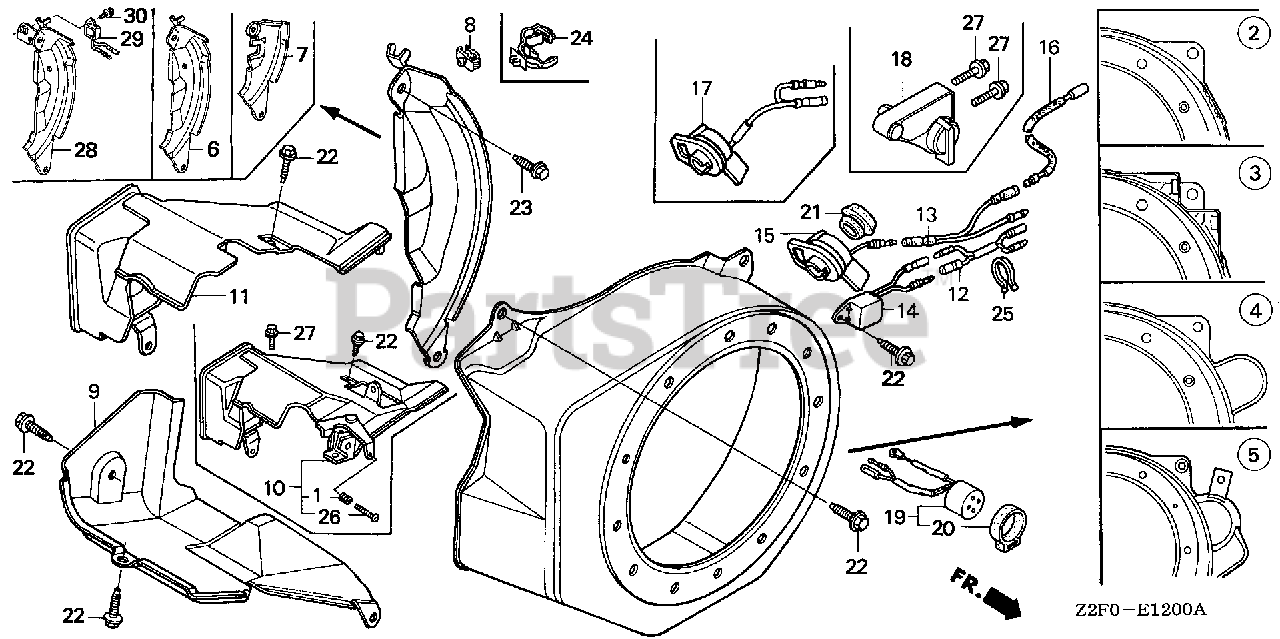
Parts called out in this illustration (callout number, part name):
2	COVER, FAN *R280* (POWER RED)
6	PLATE, SIDE
15	SWITCH ASSY., ENGINE STOP
22	BOLT, FLANGE (6X12) (CT200)
23	BOLT, FLANGE (6X20) (CT200)
